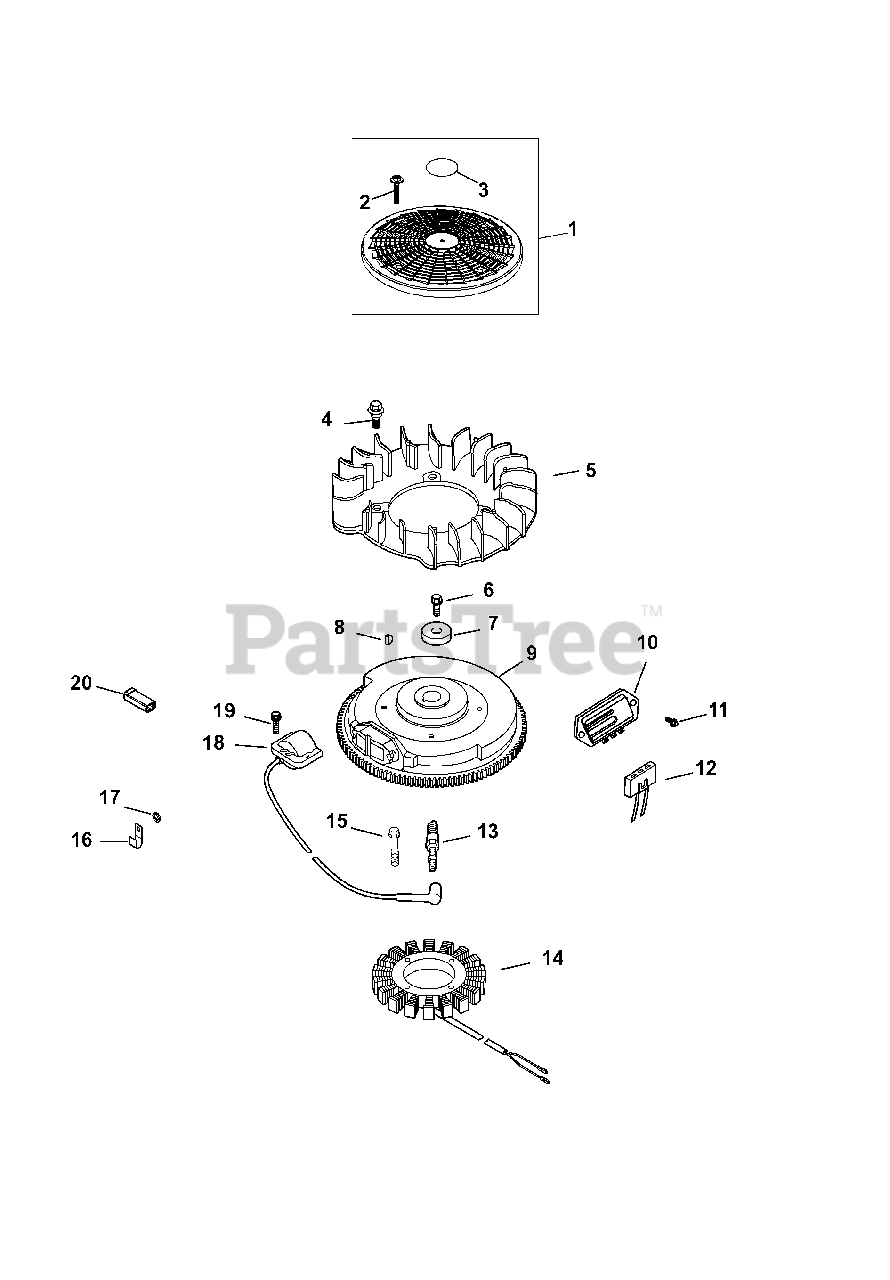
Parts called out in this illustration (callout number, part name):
1	Kit, Grass Screen (Includes 2, 3)
2	Screw, Flg Sems M4 x 0.7 x 25
3	Decal, Grass Screen
4	Bolt, Shoulder
6	Screw, FLG M10X1.5X45
7	Washer, Flat 13/32"
8	Key, 3/16" x 5/8"
10	Rectifier-Regulator
11	Screw, Hex Flange Hi-Lo
12	Connector (3 Contact)
13	Plug, Spark
14	Kit, 15 Amp Stator(Includes KH-25 452 01-S)
15	Screw, THD FRM M5 x 0.8 x 25
16	Clip, Cable
17	Washer, Flat, 1/4"
18	Kit, Module, Ignition (CDI Fixed)
19	Screw, FLG THD FRM M5 x 0.8 x 20
20	Connector (1 Contact)
